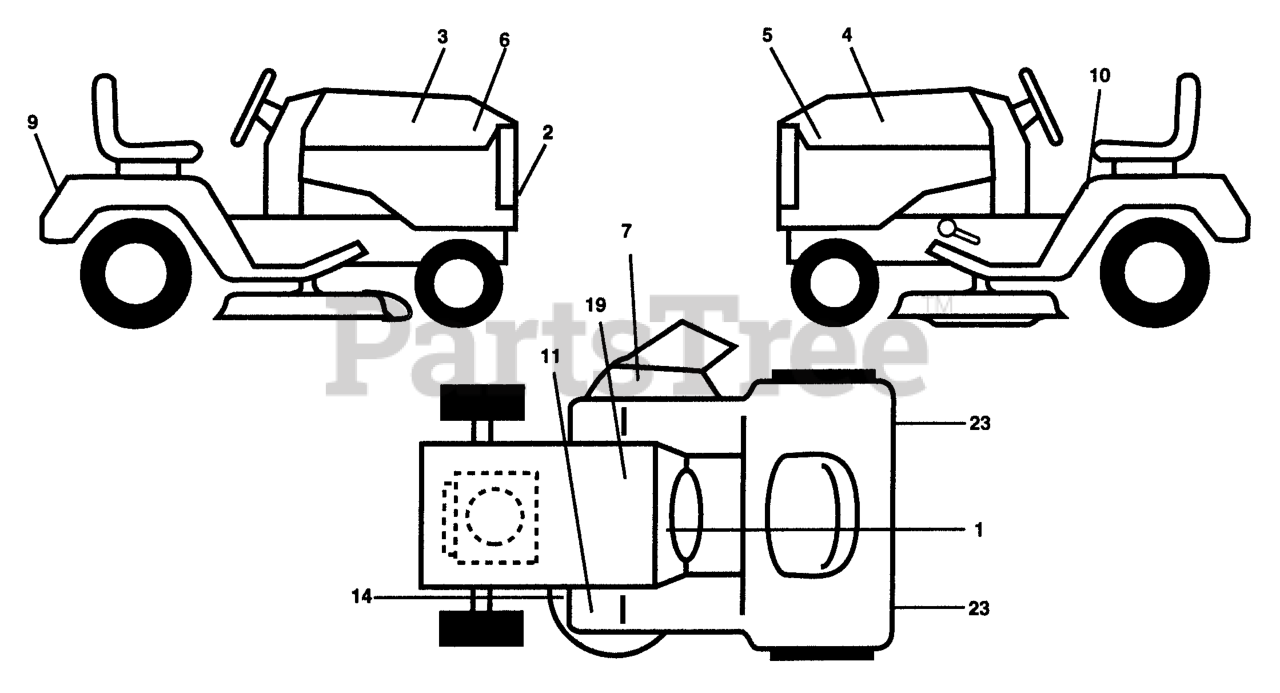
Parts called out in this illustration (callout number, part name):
2	DECAL GRILL HUSQ NLA
3	DECAL-HOOD R.H.
4	DECAL-HOOD L.H.
7	DECAL WARNING (ENGLISH/FRENCH)
9	DECAL FENDER NLA
10	DECAL CAUTION
23	REFLECTOR-TAIL YT
